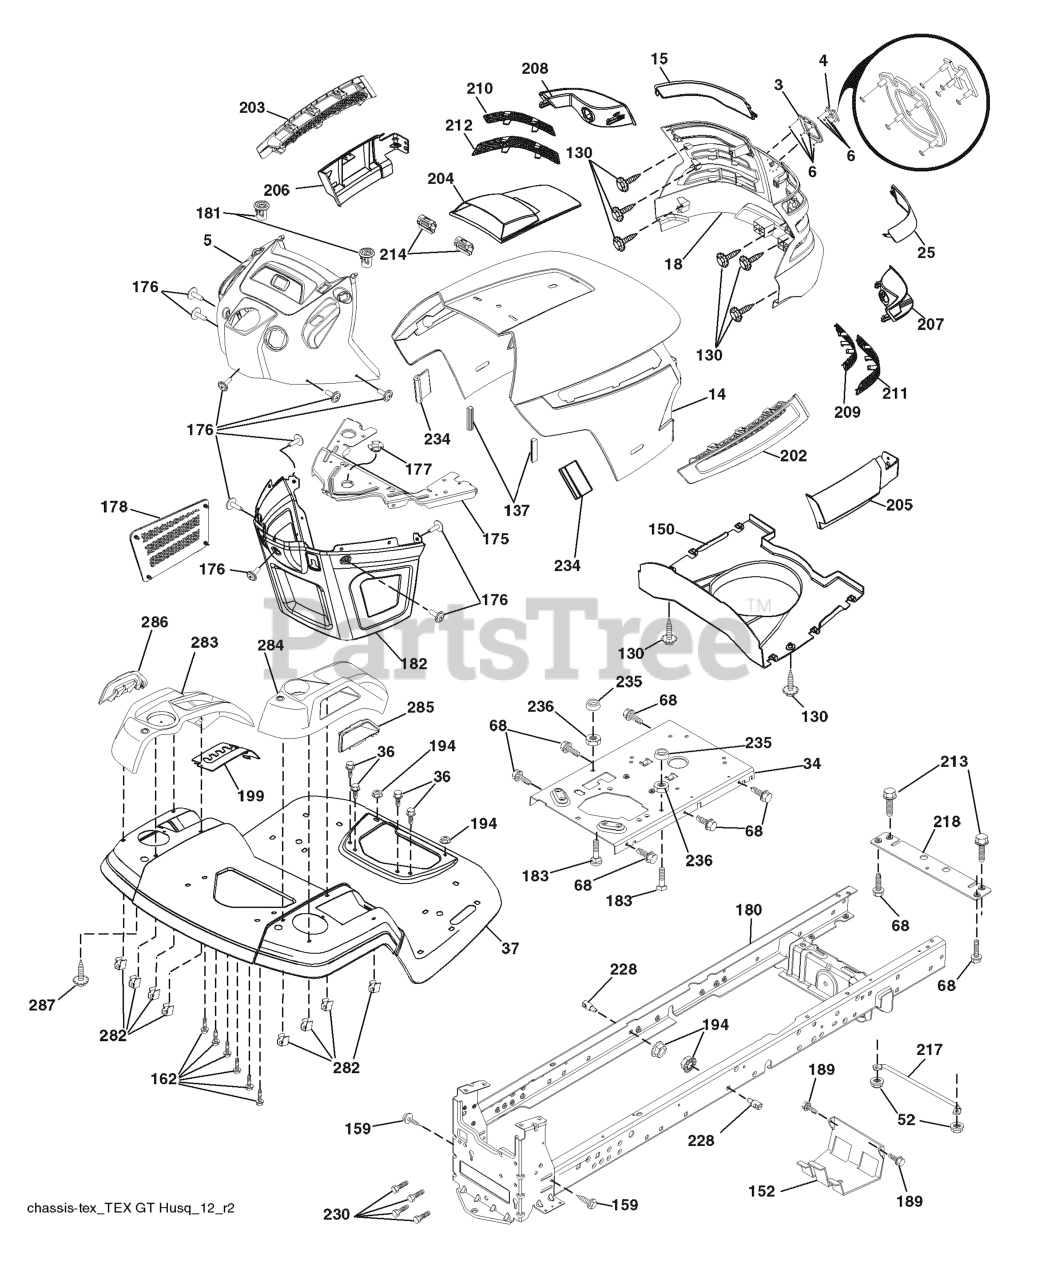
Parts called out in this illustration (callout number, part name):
3	TRIM.HUSQ.TG/CRD.SERVICE
4	RP LOGO
5	DASH.ASM.HUSQ.GT.E.RECT.W/CK
6	NUT PUSH M
14	HOOD
15	LENS.LH.TEX.GT.HUSQ.CL
18	GRILL.ASM.HUSQ.TG/CRD.W/TRIM
25	LENS.RH.TEX.GT.HUSQ.CL
34	PLATE.ENGINE.WELDED.CHASSIS
36	SCREW 5/16"
37	RP FENDER.TLT.FS.W/CPH.422
52	LOCKNUT
68	Screw Thdrol 5/16-18 x 1/2
130	SCREW.#10 X 0.750.BOS
137	BUMPER DASH
150	AIR.DUCT.HOOD.TEX.GT.HUSQ
152	SHIELD.BROWNING.W/TEX
159	SCREW, 3/8-16X3/4
175	PLATE.CROSSMEMBER.HUSQ
176	SCREW.#10-24X5/8.RN.QU
177	BUSHING, STEERING
178	CARGO.ASM.NET.TXGT.W/C
180	CHASSIS
181	BUSHING.MNT.FEND.CRGO.
182	DASH.LOWER.COMMON.12V.ADAPTOR
183	BOLT.5/16-18X1-1/4 FULL.THREAD
189	SCREW
194	NUT LOCK HEX FLANGE 5/16-18
199	PLATE.DECK.LIFT.HUSQ.LT
202	VENT.SIDE.HOOD.HUSQ.RH.GREY
203	VENT.SIDE.HOOD.HUSQ.LH.GRAY
204	HOOD VENT
205	SKIRT.HOOD.SIDE.HUSQ.RH.GREY
206	SKIRT.HOOD.SIDE.HUSQ.LH.GREY
207	BEZEL.RH.TEX.GT.HUSQ
208	BEZEL.LH.TEX.GT.HUSQ
209	INSERT.HEX.GRILL.HUSQ.GREY
210	INSERT.HEX.GRILL.HUSQ.
211	INSERT.HEX.GRILL.HUSQ.
212	INSERT.HEX.GRILL.HUSQ.
213	BOLT
214	CLIP.RETAINER.TINNER.
217	ROD.PIVOT.HOOD
218	X-PIECE.HOOD.STOP.NON/
228	STUD.FASTNER.W/ANTI-ROTATE
230	SHOULDER BOLT 5/16-18TT
234	BUMPER.HOOD.TEX.HUSQVARNA
235	SPACER FENDER
236	NUT.CENTERLOCK.5/16-
282	CLIP.RETAINER.CONSOLE.LT.HUSQ
283	CONSOLE.DECK.LIFT.HUSQ.N/FR.GR
284	CONSOLE.CNTRL.
285	CONSOLE INSERT RH
286	CONSOLE.INSRT.LH.HUSQ.LT.BLACK
287	SCREW 1/4X20
